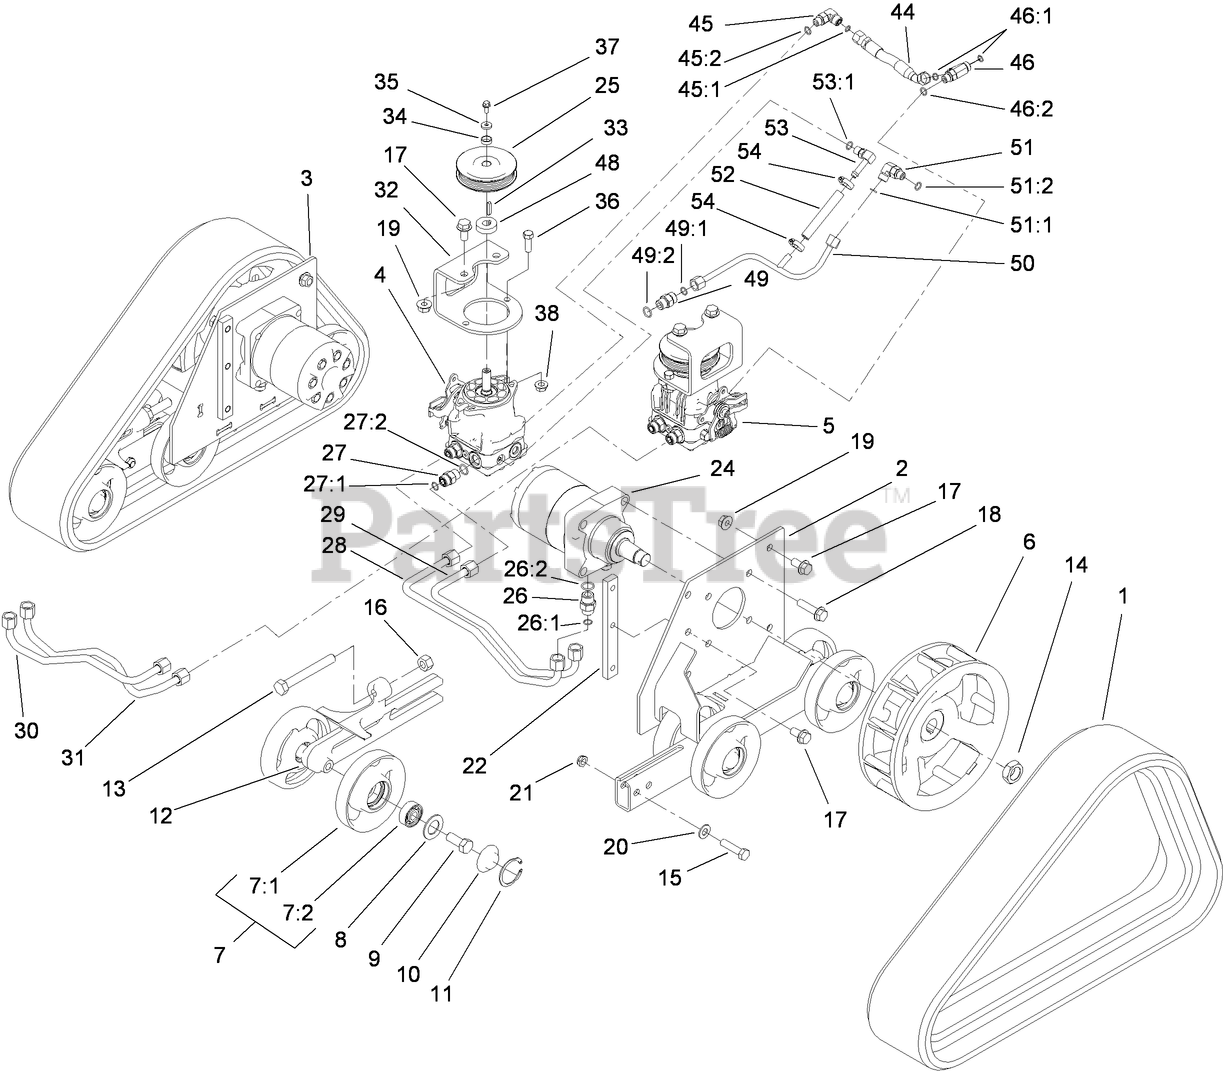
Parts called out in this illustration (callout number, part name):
1	TRACK-RUBBER
2	FRAME-TRACK, LH
3	FRAME-TRACK, RH
4	PUMP-HYD, RH
5	PUMP-HYD, LH
6	WHEEL-DRIVE
7	WHEEL-TENSIONER
7:1	WHEEL-TRACK
7:2	BEARING
8	Gasket-Bogie
9	SCREW-HH
10	CAP-WHEEL, BEARING
11	RING-SNAP, INTERNAL
12	TENSIONER-TRACK
13	SCREW-HH, TAP
14	NUT-LOCK
15	SCREW-HH
16	NUT-HEX
17	SCREW-HHF
18	SCREW-HHF
19	NUT-HHF
20	WASHER-FLAT
21	NUT-LOCK, NI
22	BAR-THREAD
24	HYD WHEEL MOTOR ASM
25	SHEAVE
26	FITTING-STRAIGHT
26:1	O-RING
26:2	O-RING
27	FITTING-STRAIGHT
27:1	O-RING
27:2	O-RING
28	TUBE-HYD
29	TUBE-HYD
30	TUBE-HYD
31	TUBE-HYD
32	BRACKET-MOUNT, PUMP
33	KEY-PUMP
34	BUSHING
35	WASHER
36	SCREW-HH
37	SCREW-HHF
38	NUT-HF
44	HOSE-HYD
45	FITTING-ELBOW, 90 DEG
45:1	O-RING
45:2	O-RING
46	FITTING-TEE
46:1	O-RING
46:2	O-RING
48	SPACER
49	FITTING-STRAIGHT
49:1	O-RING
49:2	O-RING
50	TUBE-HYD
51	FITTING-ELBOW, 90 DEG
51:1	O-RING
51:2	O-RING
53	FITTING-ELBOW, 90
53:1	O-RING
54	CLAMP-HOSE
